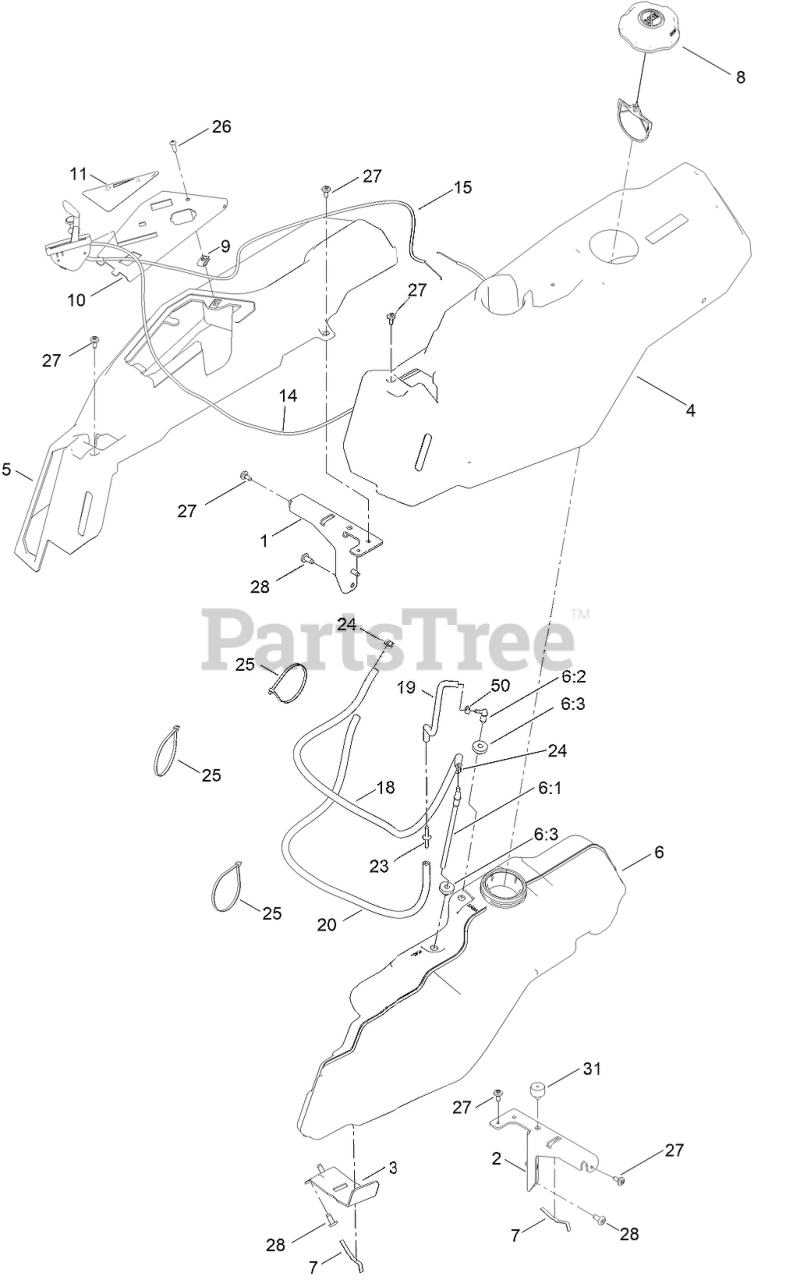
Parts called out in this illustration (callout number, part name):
1	SUPPORT-POD, RH
2	SUPPORT-POD, LH
3	SUPPORT-TANK, FUEL
4	POD-LH
5	POD-RH
6	TANK-FUEL ASM
6:1	CONNECTOR-ELBOW, 90 DEG
6:2	FITTING-ELBOW 90
6:3	BUSHING
7	SPRING
8	CAP-FUEL, RATCHETING
10	PANEL - CONTROL
11	DECAL-PANEL, CONTROL
14	CABLE-THROTTLE
15	CABLE-CHOKE
18	HOSE-FUEL
19	HOSE-FUEL
20	HOSE, FUEL
23	ADAPTER ORIFICE
24	CLAMP-HOSE
25	TIE-CABLE
26	SCREW-PRH
27	SCREW-SHOULDER
31	BUMPER-GROMMET
50	CLAMP-HOSE
